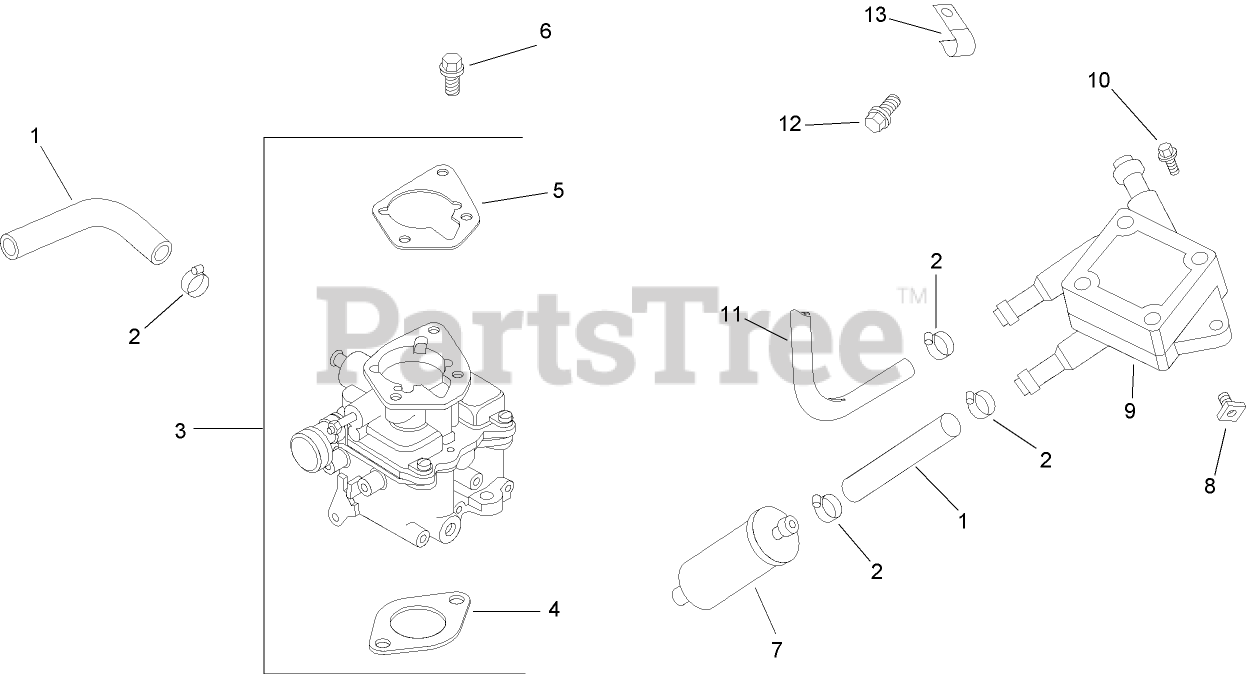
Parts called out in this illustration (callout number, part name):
1	Line-Fuel (9in)
2	CLAMP-HOSE, SPRING (1/2)
3	Carburetor Kit (Includes 4-6)
4	GASKET-BASE, AIR CLEANER
5	Gasket-Carburetor
6	SCREW-FLANGE (M6X1.0X30)
7	FILTER-FUEL
8	Nut-Plastic
9	PUMP-FUEL
10	SCREW-TAP (M6X1.7X18)
11	Line-Fuel (15-1/2in)
12	Screw-HF (M6x1.0x12)
13	CLIP-CABLE
